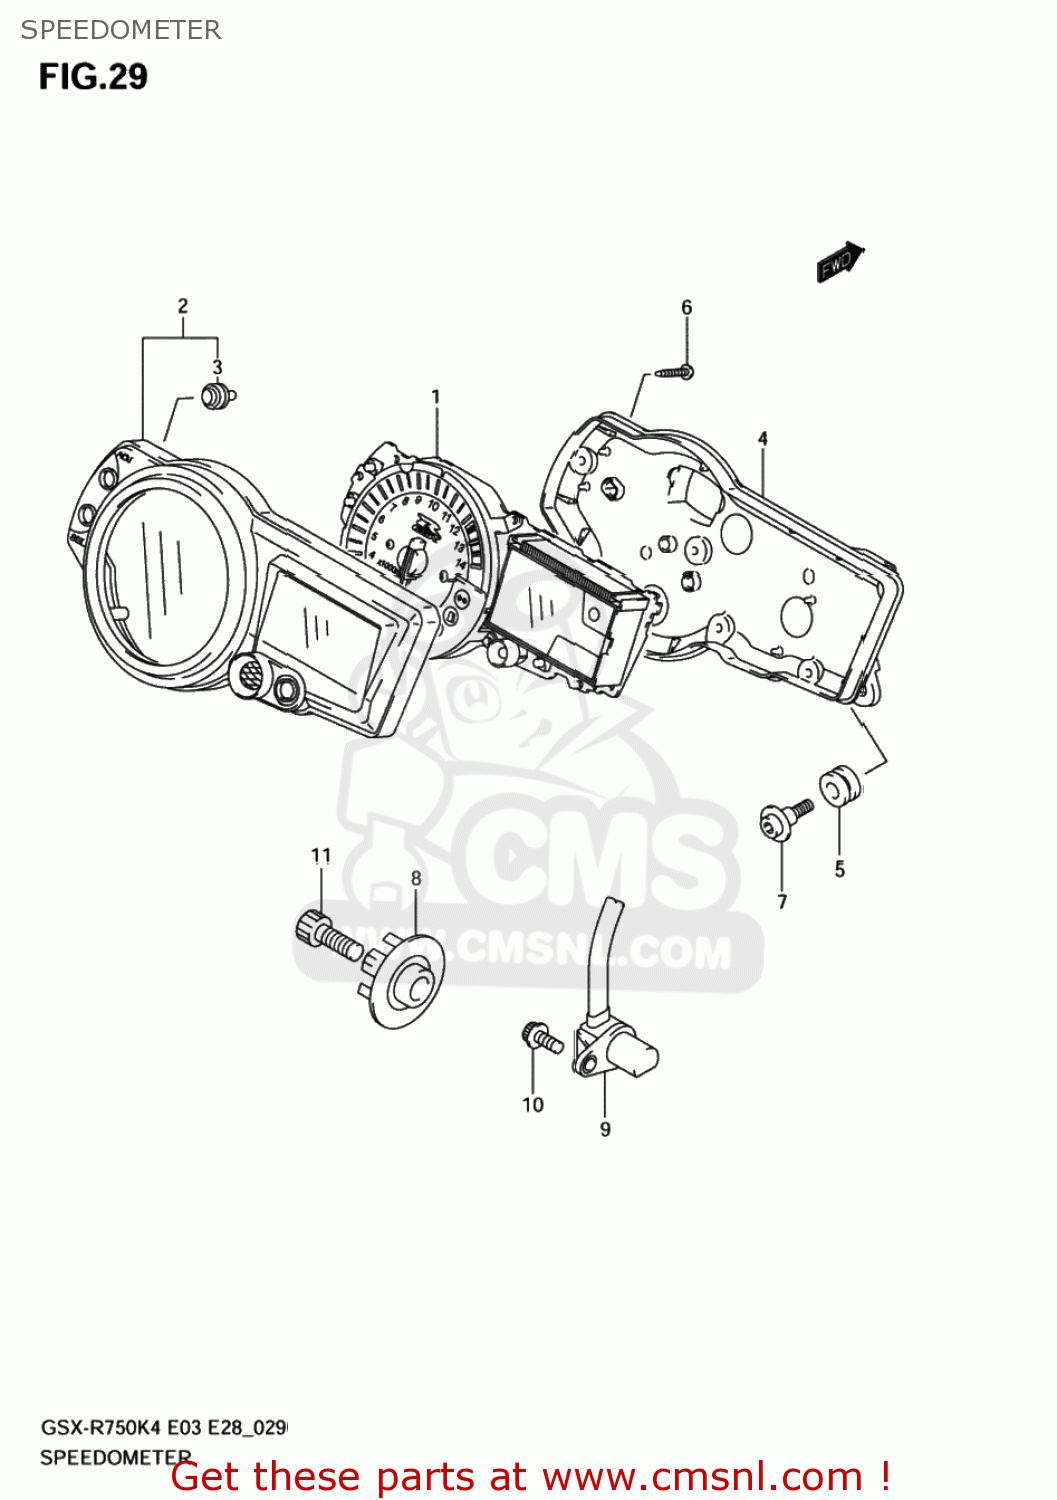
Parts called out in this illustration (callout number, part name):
1	SPEEDOMETER
2	CASE,SPEEDOMETER UPR
3	SWITCH,LEVER
4	CASE,SPEEDOMETER LWR
5	CUSHION,METER
6	SCREW(3X16)
7	SCREW,SPEEDOMETER
8	ROTOR,SPEED
9	SENSOR,SPEED
10	BOLT
11	BOLT
